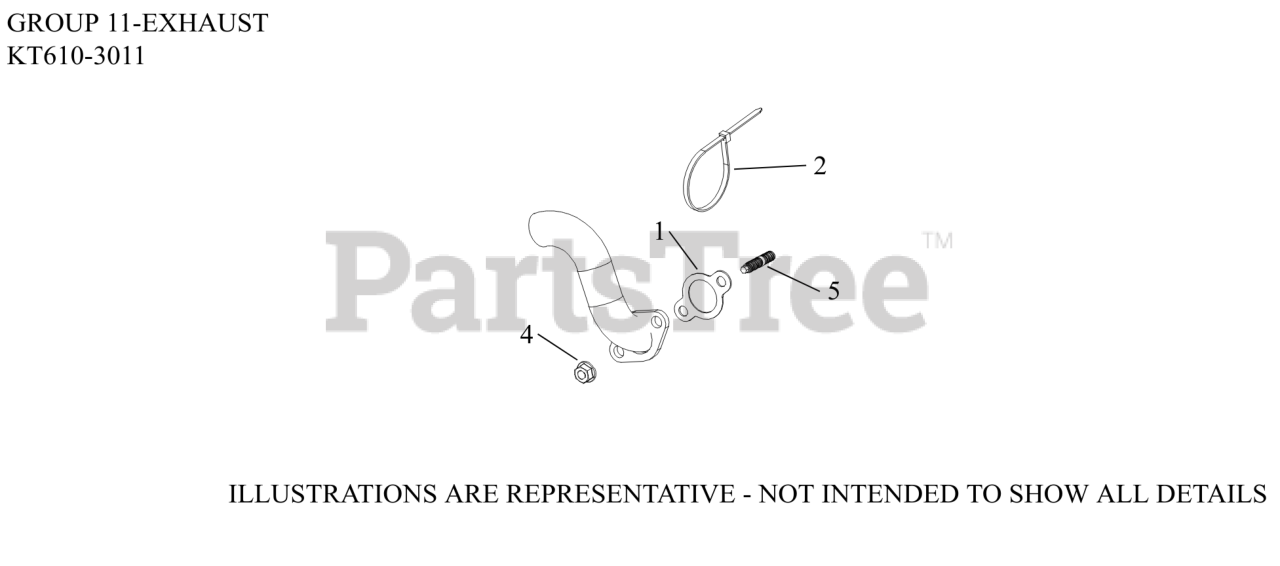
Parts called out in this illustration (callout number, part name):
1	GASKET, EXHAUST
4	NUT, HEX FLANGE LOCK (M8)
5	STUD, EXHAUST
